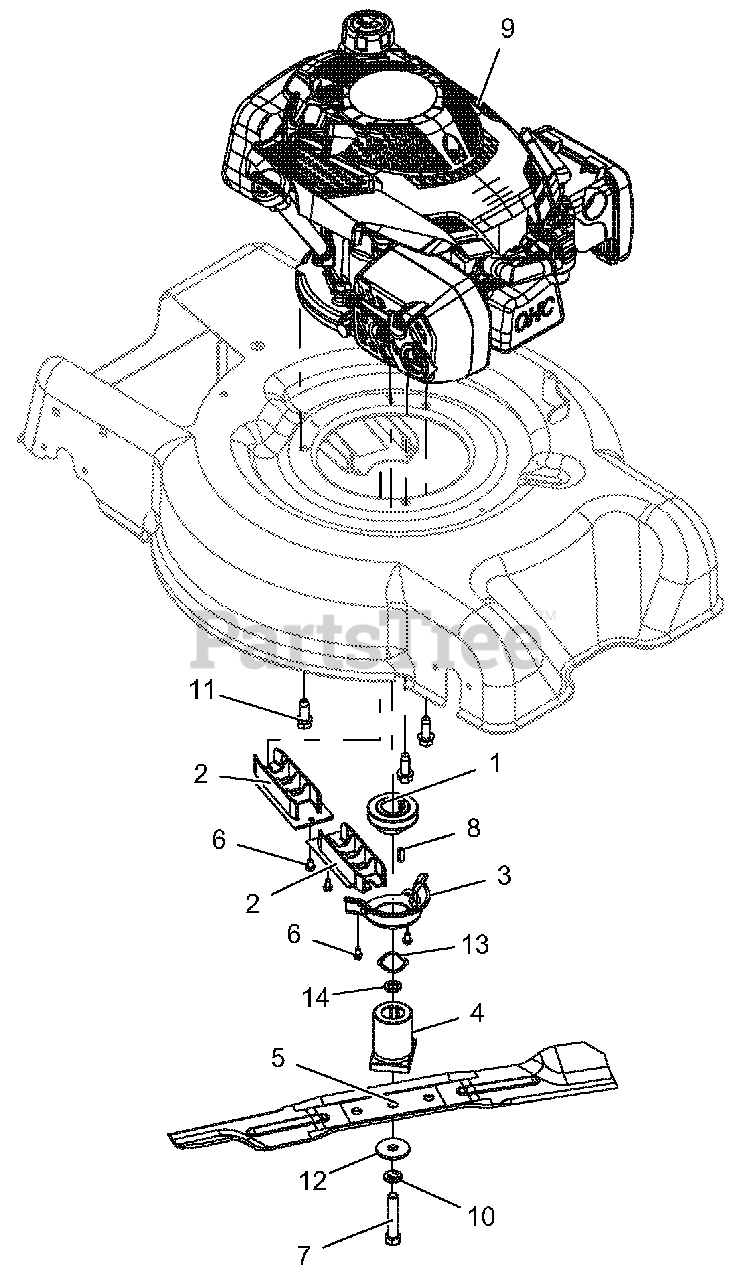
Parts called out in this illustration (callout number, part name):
1	PULLEY, GROUND DRIVE, LM
2	GUIDE, BELT INNER
3	GUIDE, BELT CRANK
4	ADAPTER, BLADE
5	BLADE, MOWER 21" HIGH LIFT
6	SCR-TAP 10-24X.375 PRE-COAT 80
7	@BLT-HEX .4375-20X2.25 GR8 YWZ
8	KEY-SQ .188X.188X.625
9	ENGINE, SUBARU 175CC VERT
10	@WSHR-LK .44X.109 REG YWZC
11	@SCR-TAP .38-16X1.00 HWH TR YZ
12	WSHR-FL-STL .4375X1.50X.125 YZ
13	WASHER - WAVE 1.09X1.37X.016
14	WSHR-FL-STL .459X.750X.105 YZC
